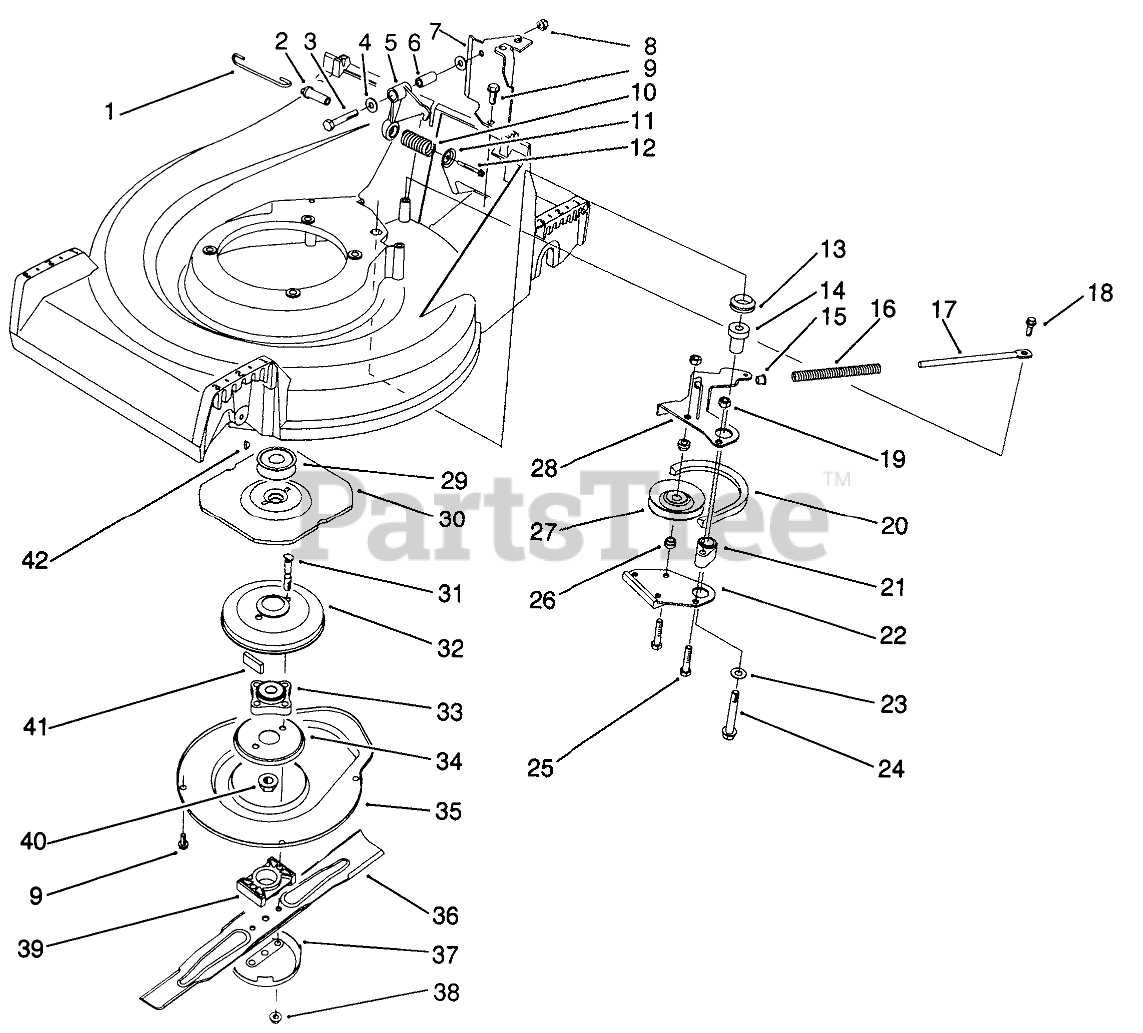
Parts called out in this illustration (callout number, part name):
1	CONTROL LINK
2	SPRING PIN
3	SCREW-HH
4	WASHER-PLAIN
5	CRANK
6	STRAIGHT BUSHING
7	Bracket-Cable Support
9	SCREW-HWHTF
10	COMPRESSION SPRING
11	RETAINER-SPRING
12	SCREW-HWHTF
13	V-RING SEAL
14	BBC PM BUSHING
15	SPACER
16	COMPRESSION SPRING
17	SPRING ROD
18	SCREW-SHOULDER
19	NUT-LOCK, NI
20	V-BELT
21	BRAKE PLATE HUB
22	BRAKE SHOE
23	WASHER-PLAIN
24	3/8-16 X 2-3/4 CAPSCR
25	SCREW-HH
26	IDLER PULLEY HUB
27	PULLEY-IDLER
28	Lever
29	PULLEY
30	FLYWHEEL - BBC
31	BOLT-BLADE
32	BRAKE DRUM
33	HUB ASM
34	Screen-BBC
35	Cover
36	Key
37	CUP-SCALP, ANTI
38	NUT-LOCK
39	SPACER-BLADE
40	Nut-Lock
41	DAMPENER-VIBRATION
42	KEY-WOODRUFF
